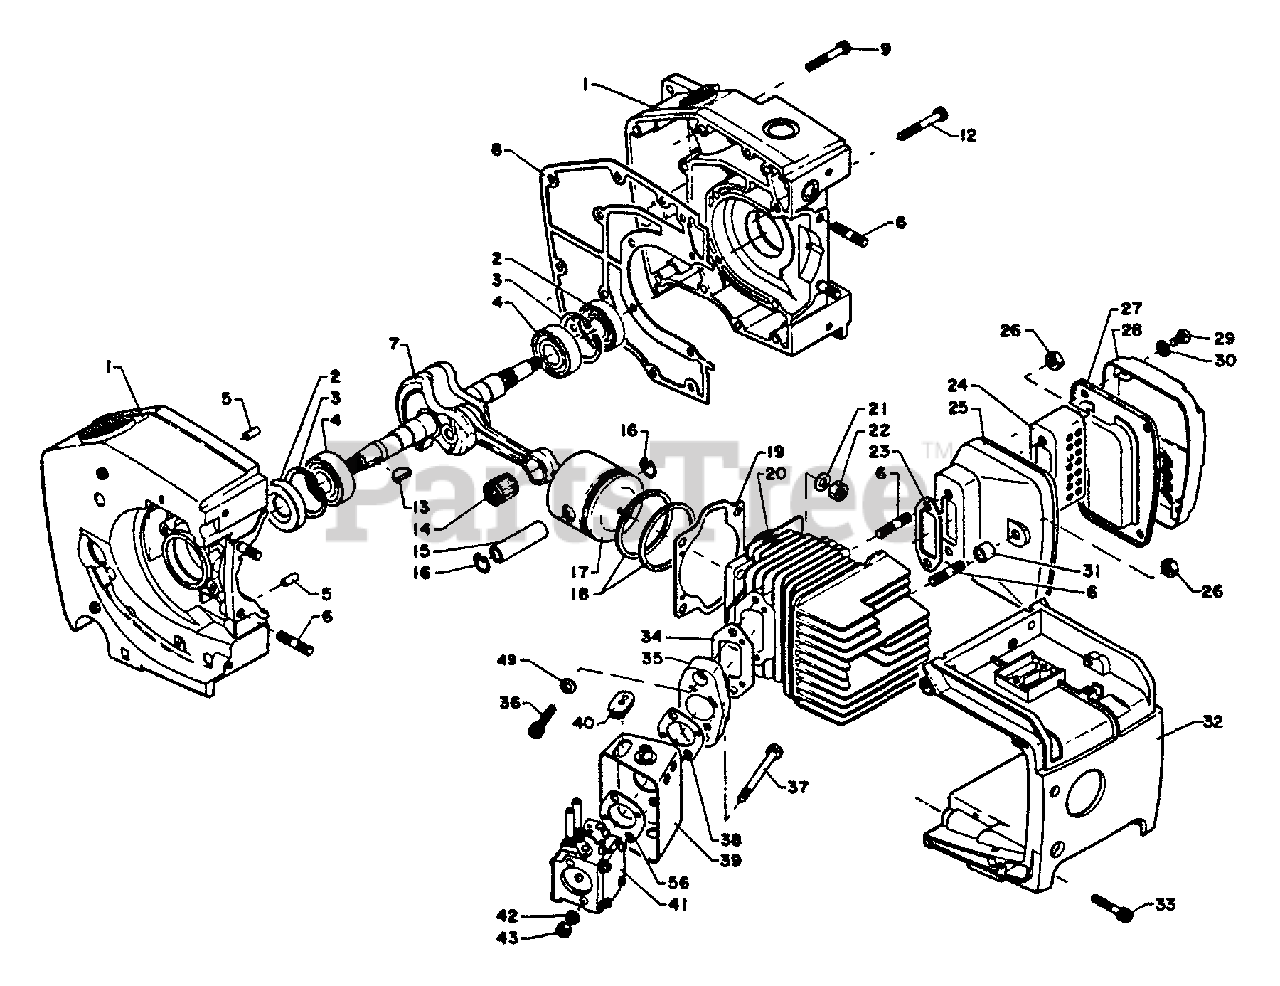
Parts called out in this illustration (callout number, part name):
1	CRANKCASE KIT
2	SEAL, OIL 18
3	RING, SNAP 35
4	BEARING, BALL 6202
5	PIN, LOCATING 5×10
7	CRANKSHAFT ASSY
8	GASKET, CRANKCASE
9	BOLT 5×30
12	BOLT M5×35
13	KEY, WOODRUFF - 3×14
14	BEARING, NEEDLE
15	PIN, PISTON
16	RING, SNAP
17	PISTON
18	RING, PISTON
19	GASKET, CYLINDER
20	CYLINDER
21	WASHER 6.5×11.5×0.8
22	NUT, HEX M6
23	GASKET, EXHAUST
24	BAFFLE, MUFFLER
25	MUFFLER
26	LOCKNUT - 6
27	PLATE
28	LID, MUFFLER
29	SCREW 5×8
30	WASHER, LOCK 5 MM
32	COVER, ENGINE
33	BOLT 5×20
34	GASKET, INTAKE
35	CASE, CARBURETOR
37	BOLT
38	GASKET, INTAKE
39	CASE, CARBURETOR
40	GROMMET
41	CARBURETOR - HS-166A
41	CARBURETOR
42	WASHER 5.2×8×0.8T
43	LOCKNUT - 5
56	GASKET
